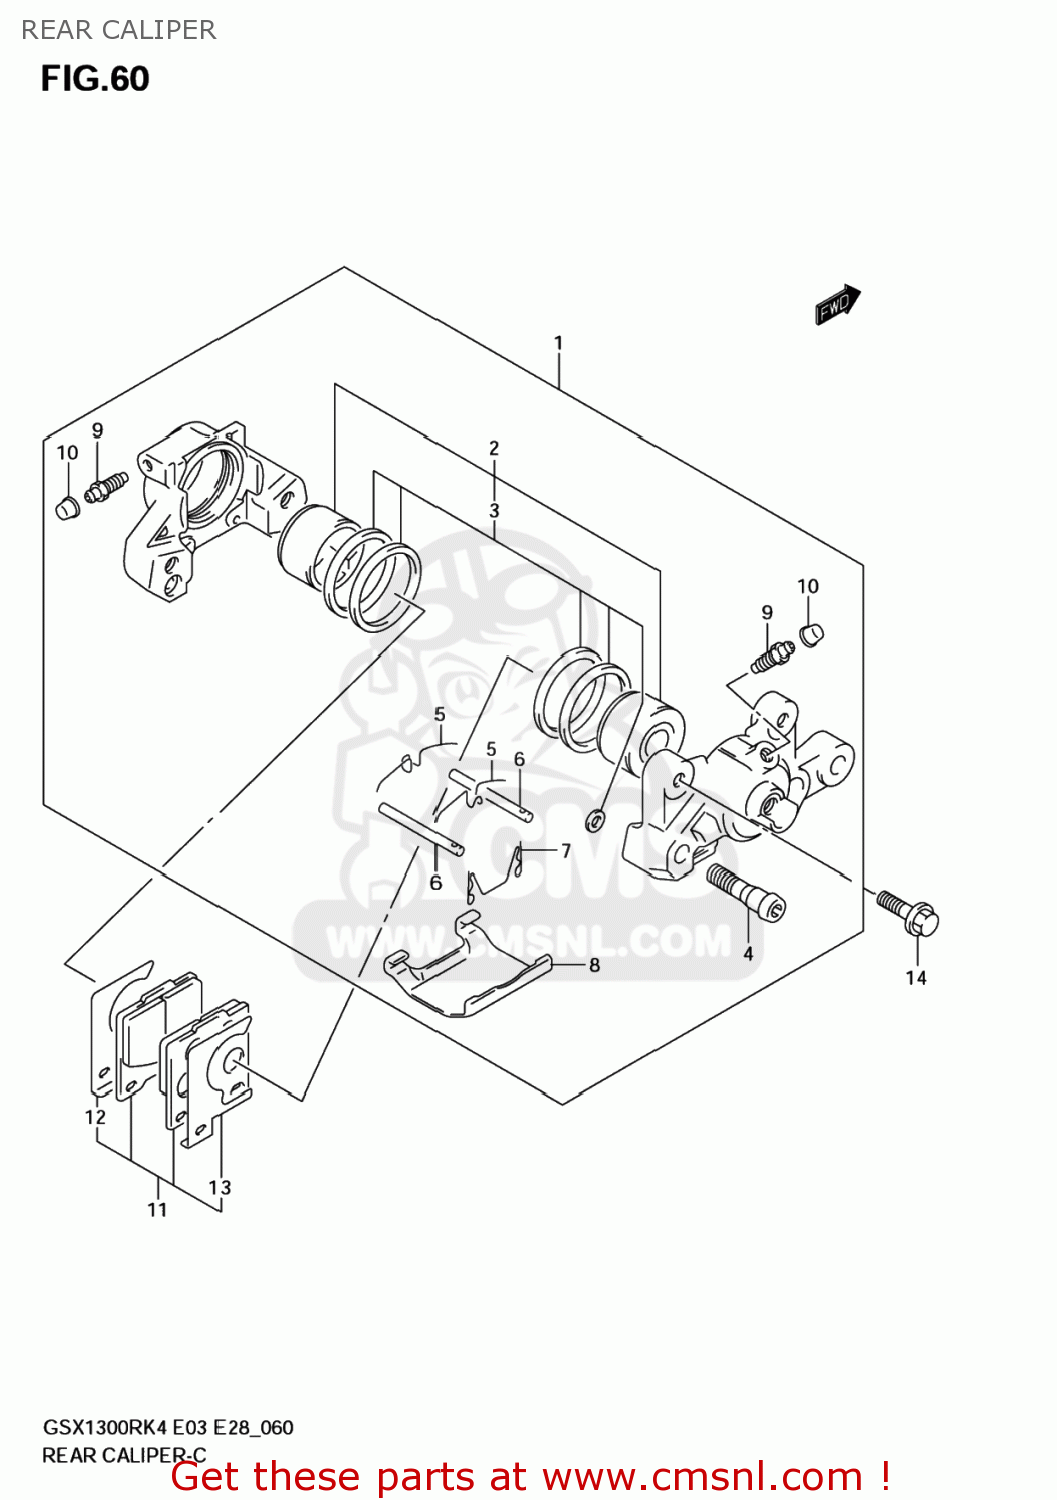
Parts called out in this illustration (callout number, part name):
1	CALIPER ASSY,RR(GOLD)
2	PISTON SET
3	SEAL SET,PISTO
4	BOLT,HOUSING
5	SPRING
6	PIN,PAD
7	CLIP,PAD PIN
8	COVER
9	BLEEDER
10	CAP,BLEEDER PLUG
11	PAD & SHIM SET (NAS)
12	SHIM,INNER
13	SHIM,OUTER
14	BOLT(8X28)
